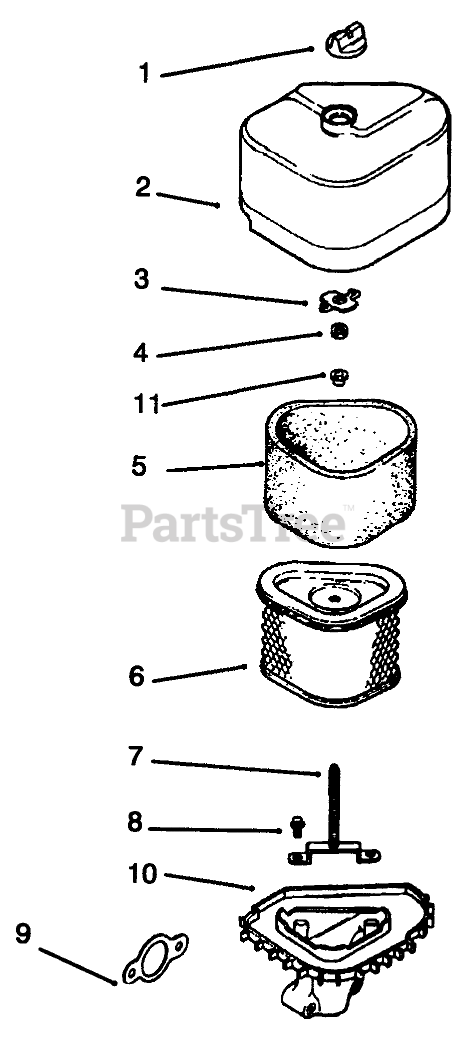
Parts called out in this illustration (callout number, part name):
1	Knob-Air Cleaner Cover
2	Cover-Air Cleaner
3	Wingnut
4	Washer
5	Element-Air Cleaner
6	Element-Precleaner
7	Stud M-6x1.0x66
8	Screw
9	Gasket-Air Cleaner
10	Base-Air Cleaner (Incl.
11	Grommet
